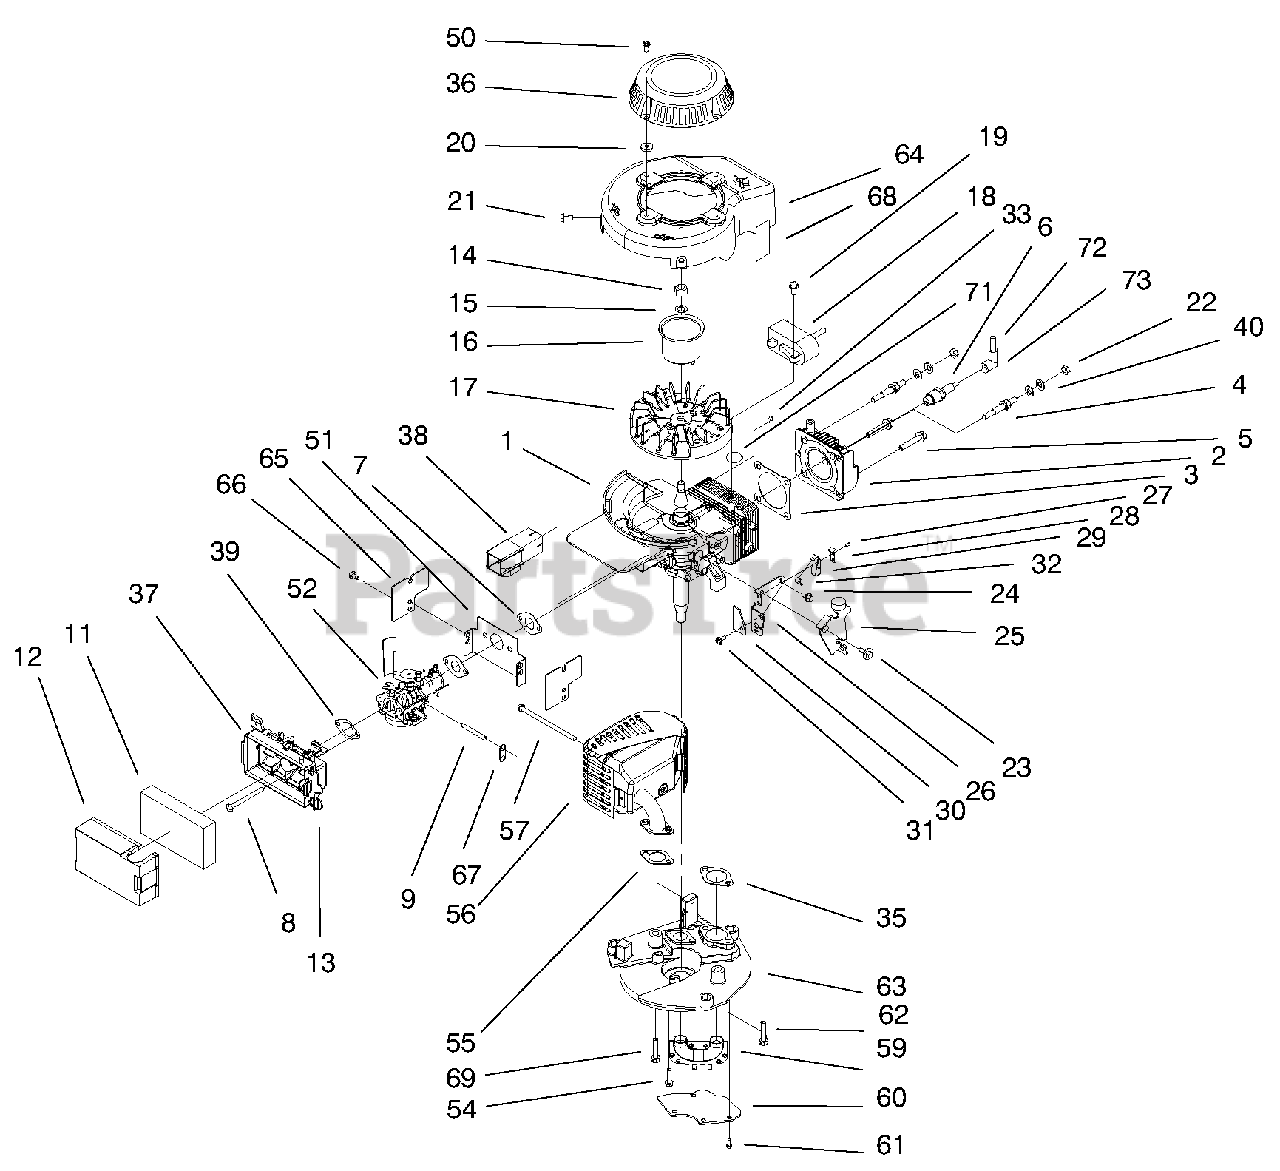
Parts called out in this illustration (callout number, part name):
1	Short Block ASM
3	Gasket-Head
6	Spark Plug
7	Intake Gasket
9	Primer Hose
11	Element-Air Filter
12	Cover-Air Filter
13	Retainer-Filter
15	Washer-Lock
16	Hub-Starter
17	Flywheel Machined Recoil
18	Ignition ASM
19	Screw-HWH
21	Screw
22	Nut-Lock
23	Shoulder Screw Brake
24	Screw (Brake)
25	ASM-Brake Plate
26	Plate-Mount Brake
27	Rivet-Self Expand Plas
28	Strap-Insulation
29	Strap-Ground
30	Stop-Ground Strap
31	Screw-Thread Forming
32	Brake Switch Lead Wire
35	Gasket-Exhaust
36	ASM-Starter
37	Air Filter Base ASM
39	Gasket-Filter Base
40	Washer-Lock
50	Screw-Sems
51	Heat Shield
52	Carburetor ASM
54	Screw-HWH
56	Muffler & Guard
59	Transfer Tube
60	Cover Plate
62	Screw-HH
63	Muffler Plate Machining
64	Shroud ASM
65	Shield-Gov Int'l
67	Retainer Hose
69	Screw-Hhd Washer
70	Washer-Lock
71	Tie Strap
72	High Tension Lead
73	Cover & Terminal
